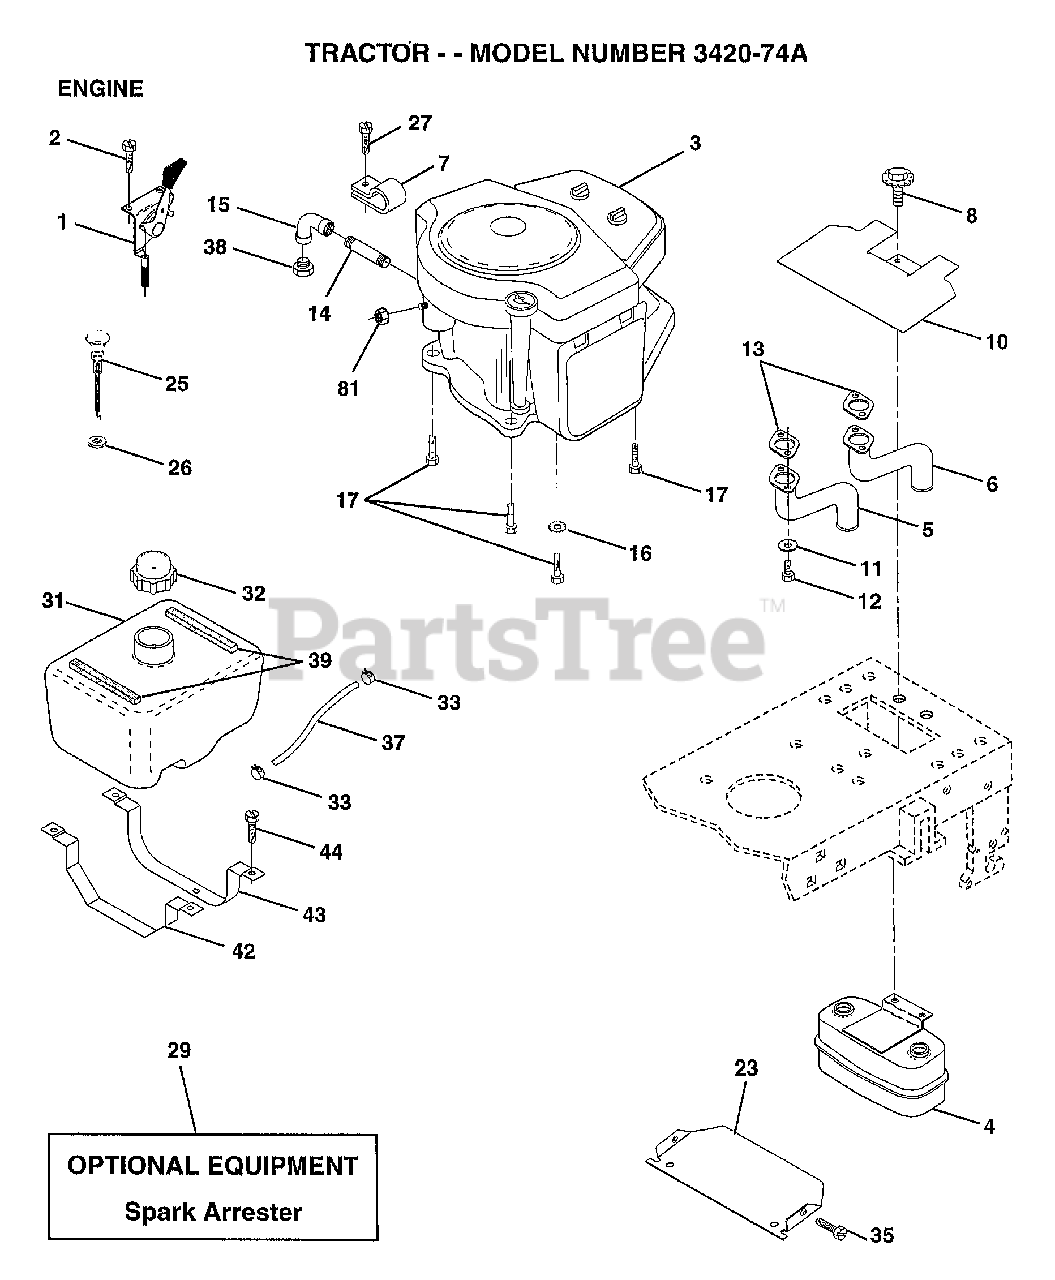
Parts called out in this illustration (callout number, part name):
2	SCREW LT
4	MUFFLER.TW.LOTONE
5	EXHAUST.B&S.18.LH
6	EXHAUST.B&S.18.RH
7	CLAMP.TUBE.DBL.EN
8	BOLT.5/16-18.UNC
10	SHIELD.HEAT.
11	LOCKWASHER
13	GASKET MUFFLER
14	PIPE NIPPLE LT
15	ELBOW
16	LOCKWASHER
17	SCREW LT
23	SHIELD-HEAT
25	"CONTROL.CHOKE.51"""
26	"NUT,KEPS 3/8-24IM"
27	"SCREW-TT,10-32 FL"
31	TANK FUEL 1.9 NAT
32	CAP ASM FUEL
33	HOSE CLAMP
35	SCREW
37	HOSE T
39	"STRIP,FORM"
42	STRAP TANK FUEL
43	STRAP TANK FRONT
44	SCREW
81	NUT
